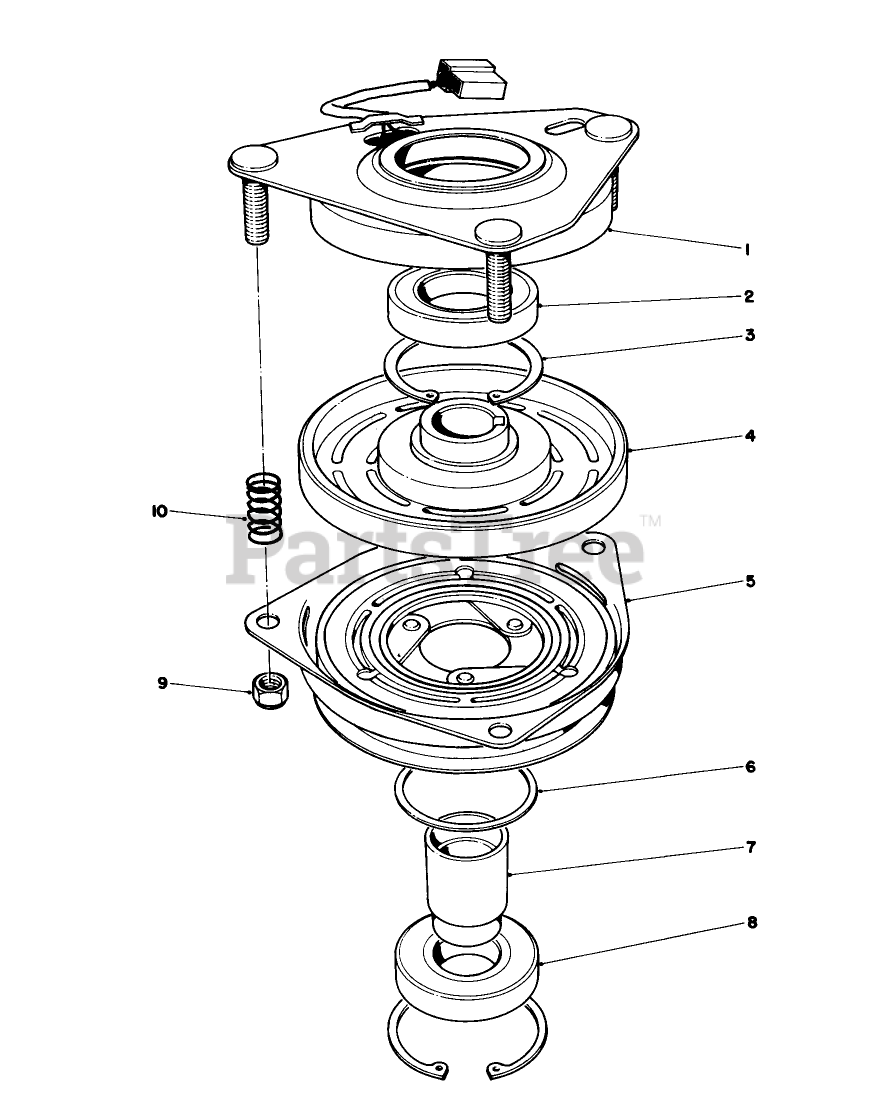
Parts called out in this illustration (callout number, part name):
1	Field Assembly (Incl. Ref. #2 & 3)
2	BEARING-FIELD
3	RING-RETAINING
4	Field Coil, Rotor & Bearing Assembly (Incl. Ref. #1)
5	Armature & Pulley Assembly (Incl. Ref. #3, 6, 7 & 8)
6	SPACER-BEARING, PULLEY
7	COLLAR-BEARING
8	BEARING-PULLEY
9	NUT-LOCK
10	SPRING
